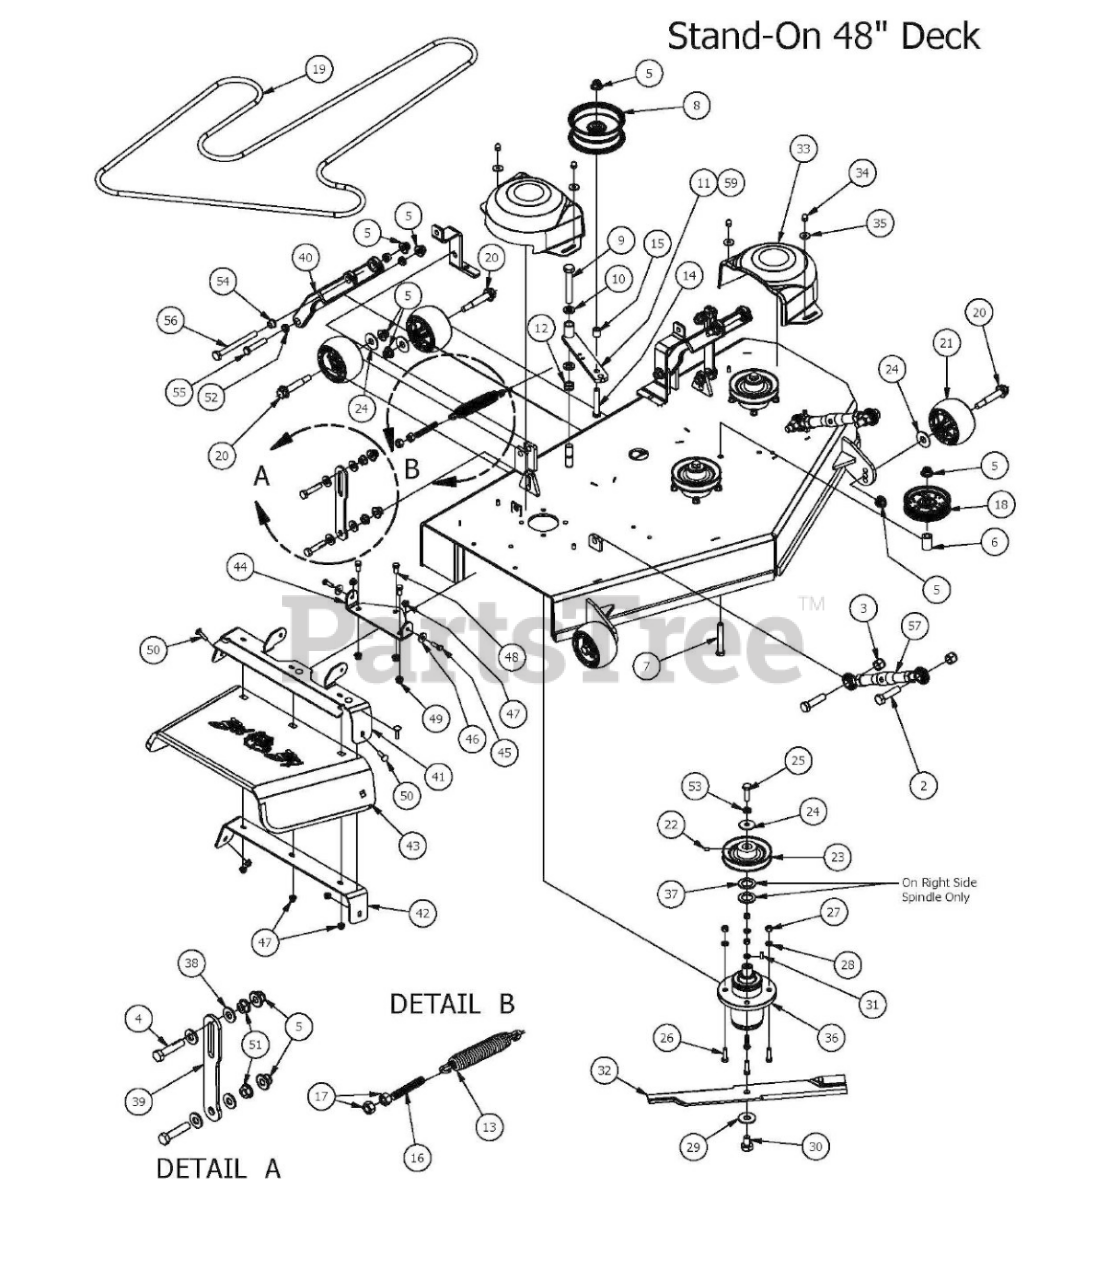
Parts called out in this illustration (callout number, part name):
1	48" 2015 Stand-On Deck (Welded Assembly)
2	5/8" x 2 1/2" Hex Bolt
3	5/8 Std NC Nylock Nut
4	1/2-13X 2-1/4 GR Hex Bolts
5	1/2-13 Nylon Flange Nut
6	Idler Pulley Standoff
7	1/2 x 3 1/2 Flange Bolt Grade 8
8	53/4" Deck Idler Pulley
9	5/8" x 4" Hex Bolt
10	.630 ID Plastic Washer
11	Deck Idler 2009 AOS
12	5/8" Nylock (1/2 Jam)
13	2009 Deck/Pump Idler Spring
14	1/2-13 x GR 5 Hex Bolt Zinc
15	Spacer 3/4 OD x 1/2 ID x 314 Length
16	All Thread-Pump Idler Tensioner
17	1/2" Hex Nut
18	4-3/4 Idler Pulley
19	B111 Belt 48" Stand-On
20	Deck Wheel Bolt
21	Anti-Scalp Rollers
22	5/16 Set Screw
23	5" Spindle Deck Pulley
24	1/2" Belleville Washer
25	1/2"-20 x 1 1/2 - Grade 5 Fine Thread Bolt
26	3/8" x 1 1/4" Hex Bolt
27	3/8-16 Hex Nuts Zinc
28	3/8" Lock Washer
29	5/8" Flat Washer
30	5/8" x 1 1/2" Grade 8 Hex Bolt (Fine)
31	1/4" x 1" Key
32	Fusion Blade
33	Pulley Cover
34	Acorn nut-pulley Cover
35	.360 ID Plastic Washer-Black
36	OUTLAW SPINDLE ASSEMBLY
37	1 1/8" Flat Spacer
38	.505 Nylon Spacer
39	Longer deck hanger
40	Deck Arm Assembly
41	Discharge Upper Chute Bracket
42	Discharge Lower Chute Bracket
43	Rubber Discharge Chute
44	Discharge Chute Hanger (Deck Mounted)
45	5/16" x 1" Bolt
46	.360 ID Plastic Washer
47	5/16" Nylon Flange Nut
48	3/8" x 3/4" Hex Bolt
49	3/8" Flange Nut
50	5/16" x 1 1/4" Carriage Bolt
51	1/2" Flange Nut
52	Flange Bushing For Lower Deck Arm
53	1/2" Lock Washer
54	Flange Bushing For Upper Deck Arm
55	1/2" x 3" Hex Bolt
56	1/2" x 5 1/2" Bolt
57	Turnbuckle
58	Stand-On Deck Stop
59	Idler Arm Assembly (5,8,11,14,15)
